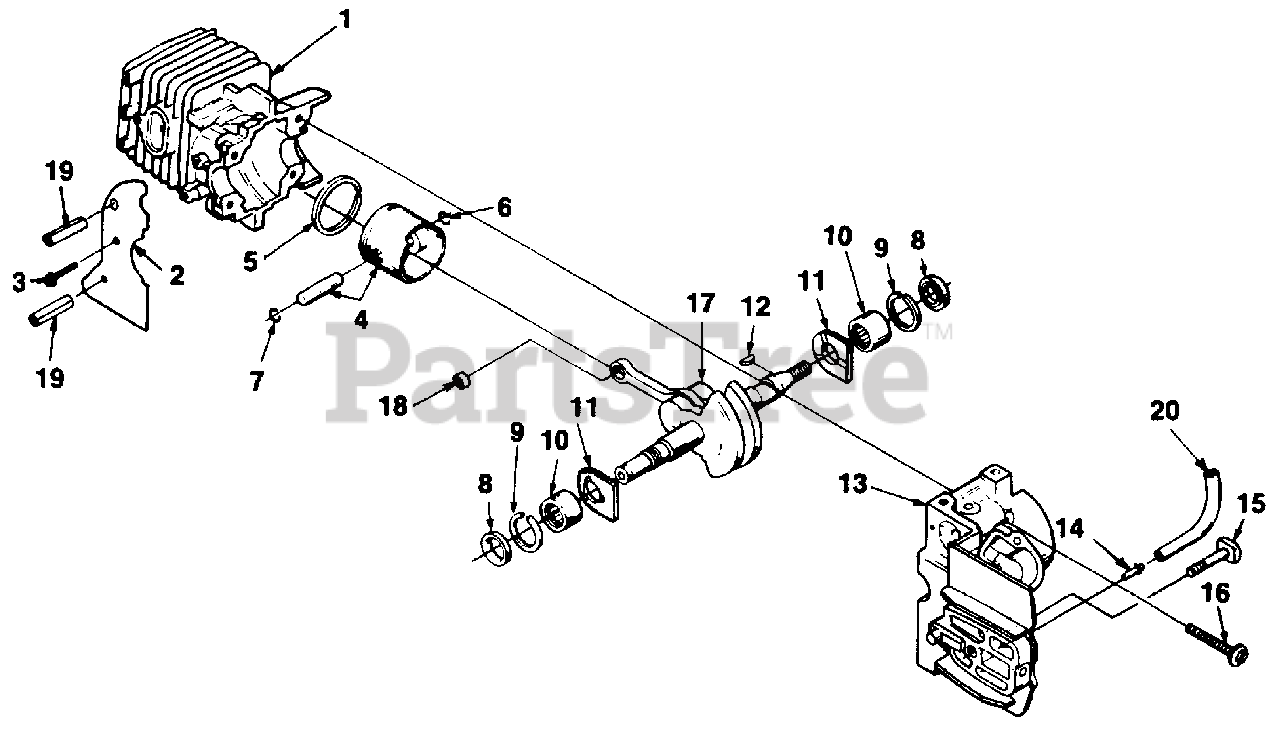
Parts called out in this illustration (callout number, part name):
1	CYLINDER
2	SHIELD- Sawdust
3	SCREW- Tapping (36-32 x 5/16")
4	PISTON & PIN ASSY.
5	RING- Piston
6	RING- Retaining
7	RING- Retaining
8	SEAL
9	SPACER
10	BEARING- Needle
11	WASHER- Thrust
13	CRANKCASE ASSY.
14	FITTING
15	BOLT- Guide bar, thd. forming
16	SCREW- Torx pan hd. (10-24 x 1 1/8")
17	CRANKSHAFT ASSY.
18	BEARING
19	PIN- Roll (5/32 x 1 1/8")(Brake Mod. Only)
20	TUBING- Rubber (Oil line) (4 1/4")
